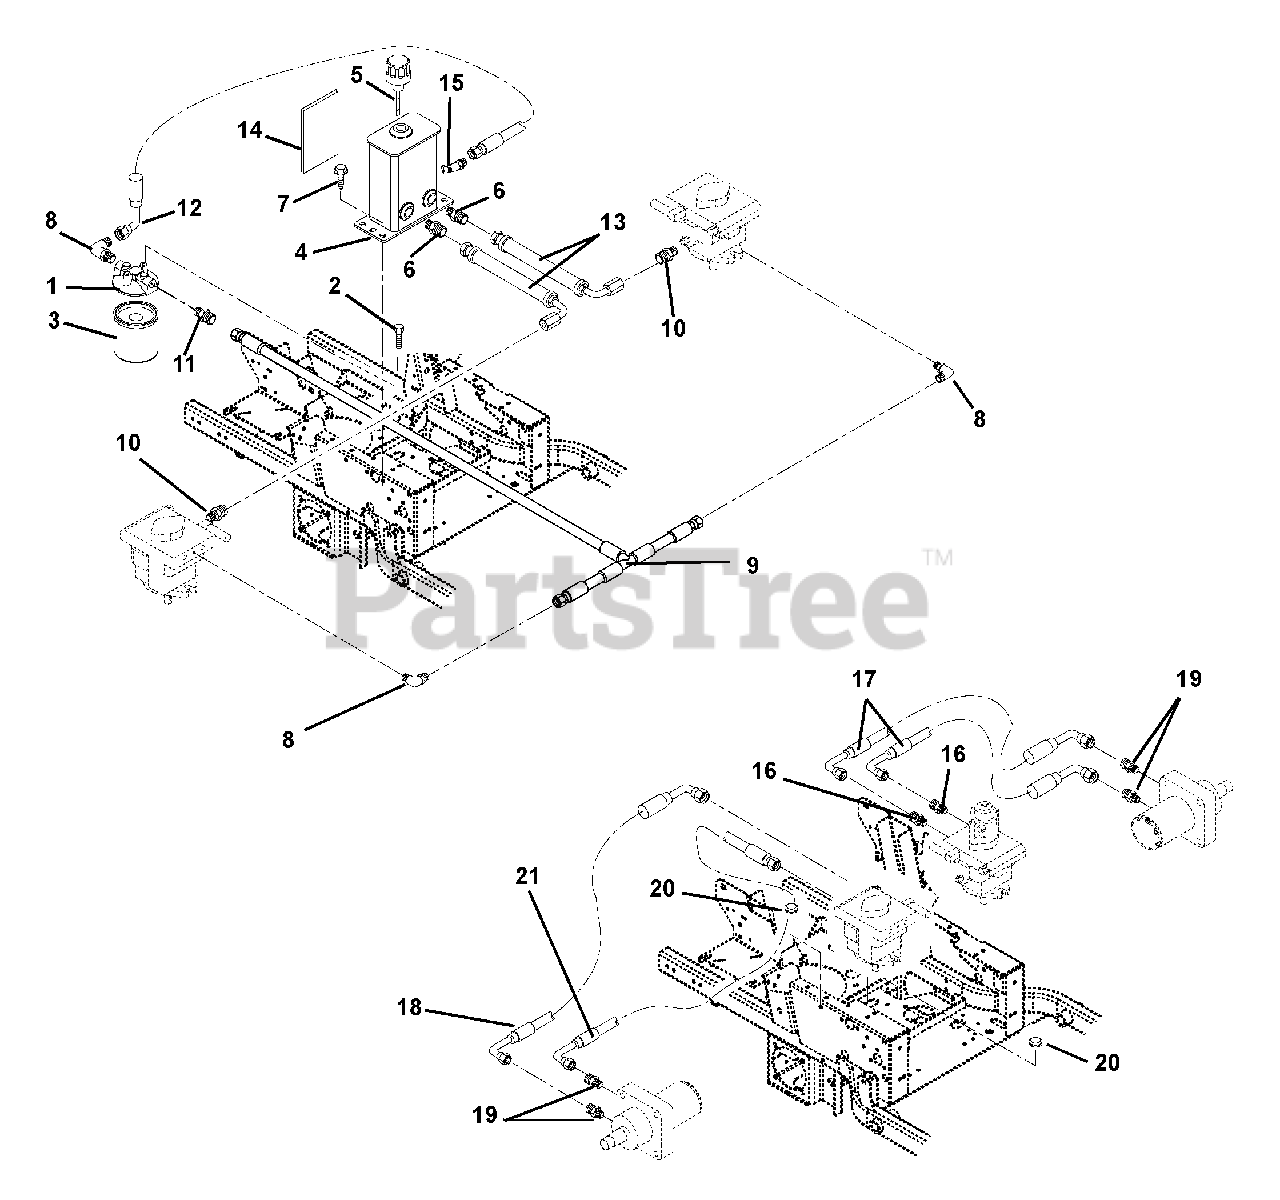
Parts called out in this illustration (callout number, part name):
1	Head, Filter
2	Bolt, Hex .25-20 x .50 Grade 5 Epoxy
3	Oil Filter
4	Tank, Hydraulic
5	Hydraulic Tank Dipstick
6	Fitting, Hydraulic Straight M8O-M4F
7	Screw, Tapping .38-16 x .75 Hex Washer Head
8	Fitting, Hydraulic
9	Hose, Hydraulic
10	Fitting, Hydraulic
11	Fitting, Hydraulic
12	Hose, Hydraulic Valve To Tank
13	Hose, Hydraulic
14	Shield, Heat 5.50 x 4.50
15	Fitting, Hydraulic 45 Degree
16	Adapter, Hydraulic
17	Hose, Hydraulic
18	Hose, Hydraulic
19	Adapter, Hydraulic
20	Grommet, 1.25
21	Hose, Hydraulic
